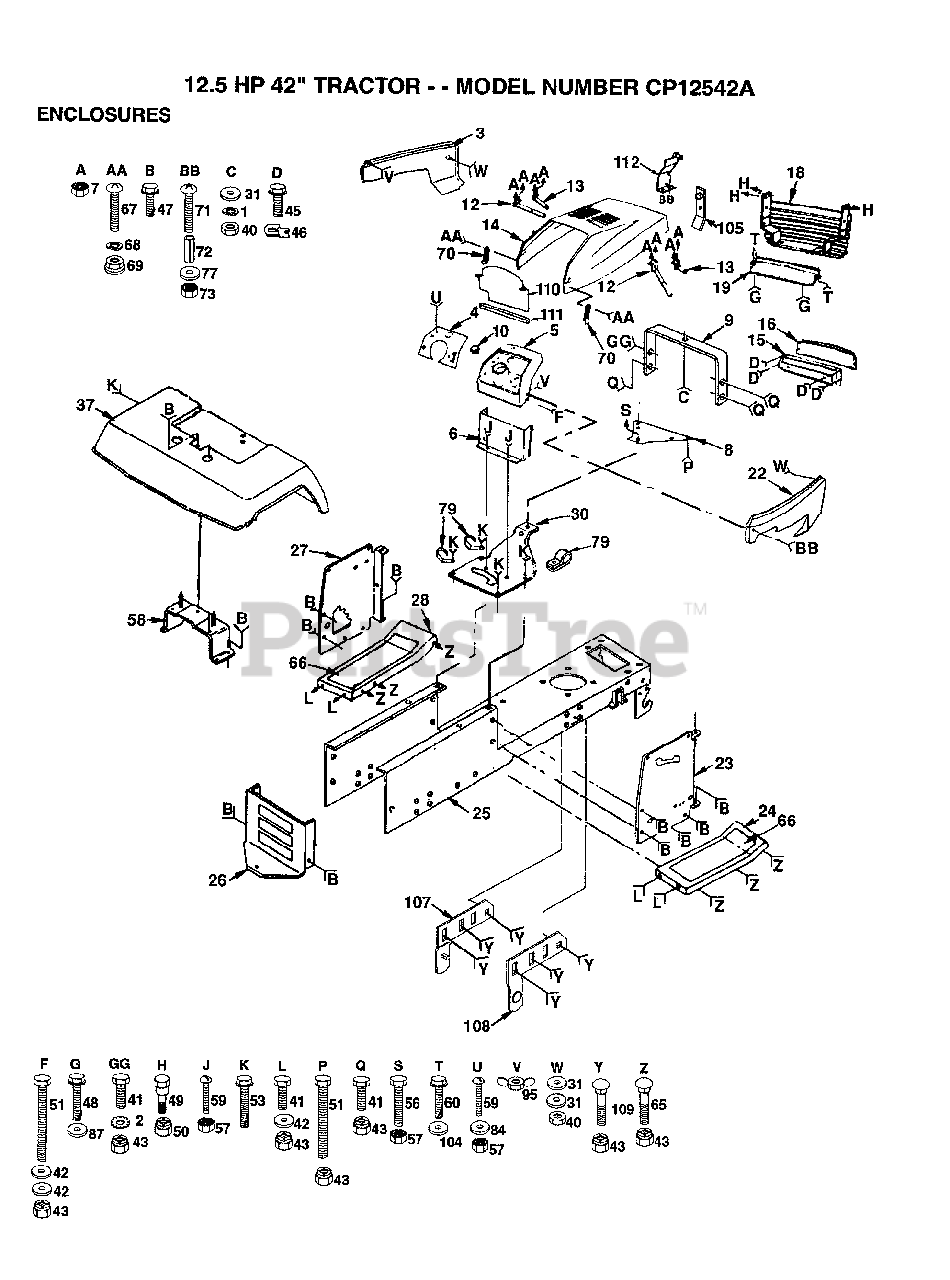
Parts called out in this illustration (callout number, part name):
1	LOCKWASHER
2	LOCKWASHER
4	DASH PLATE
7	NUT
9	SUPPORT ASS'Y
10	PLUG BUTTON T
16	LENS LT
27	DASH PANEL LH
31	WASHER PM
42	WASHER
46	J FASTENER LT
47	SCREW
48	SCREW
53	SCREW LT
56	BOLT
59	SCREW
60	SCREW HEX CRT
65	BOLT
66	FOOTREST PAD
67	SCREW
68	LOCKWASHER
69	WELDNUT
70	HOOD LATCH T
71	SCREW
72	SPACER LT
77	WASHER
79	CLIP T
84	WASHER
87	WASHER
104	WASHER
107	PIVOT BRKT LH
108	PIVOT BRKT RH
109	BOLT
110	BAFFLE HOOD VERT
111	FOAM-STRIP LT
